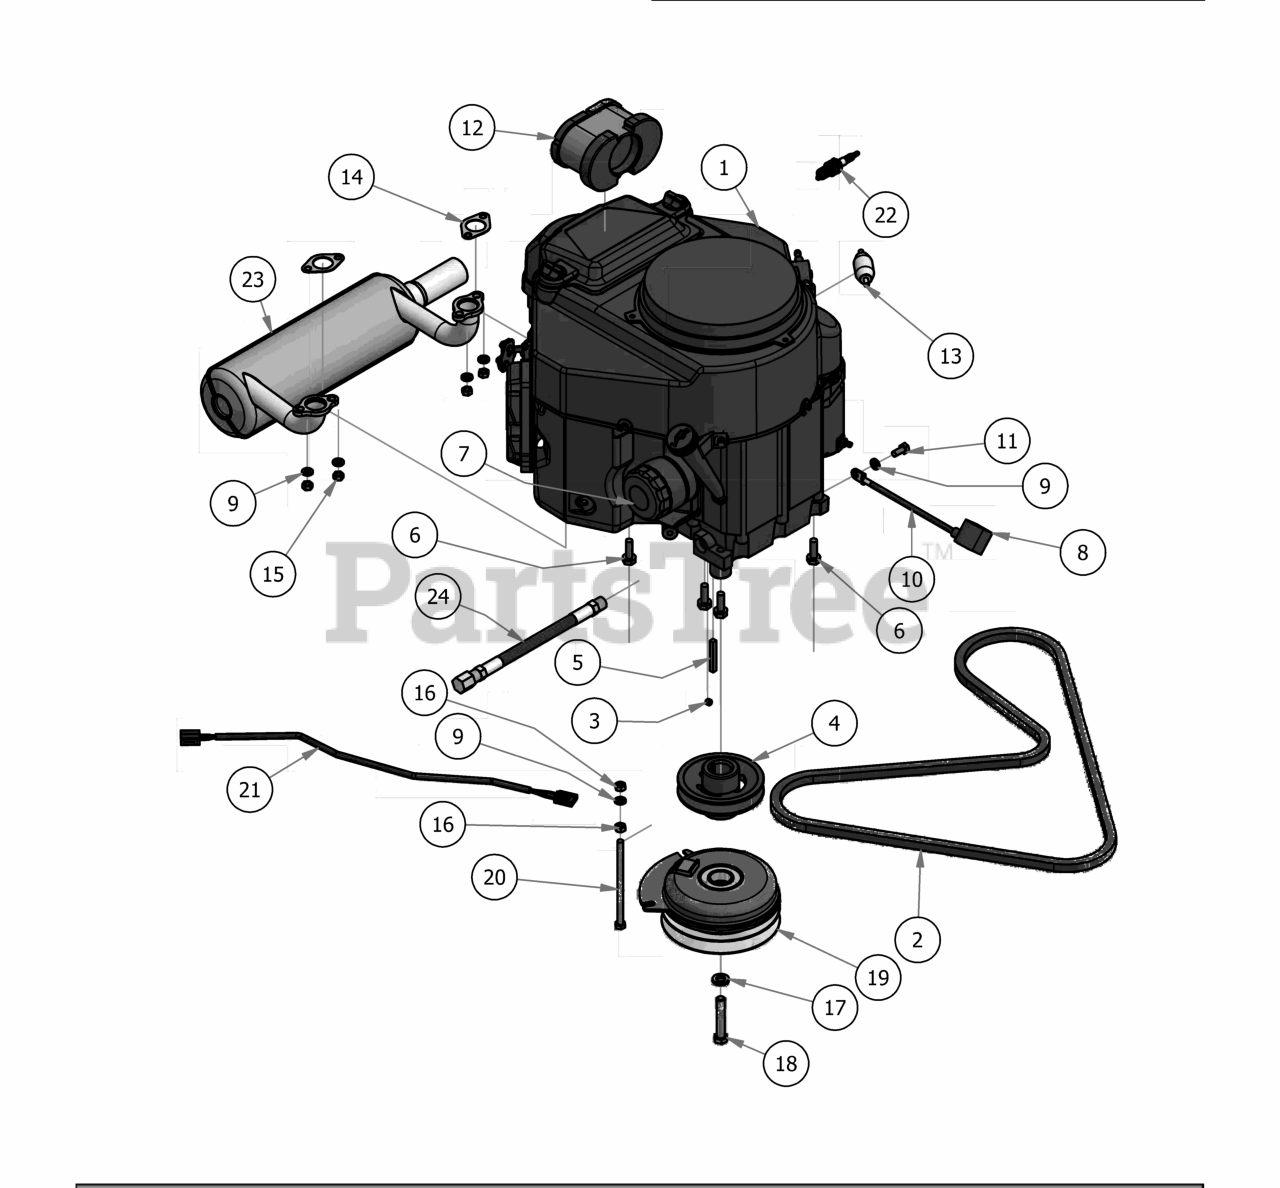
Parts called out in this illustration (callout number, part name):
1	FS730V Engine
2	75.8 Pump Belt
3	5/16 Set Screw
4	4 3/4 Motor Pulley
5	1/4 x 2 Square key Stock
6	3/8 x 1 1/8 bolt
7	Kawasaki Oil Filter
8	Black Boot For Ground Cable
9	5/16" Lock Washer
10	Ground Cable
11	M8x1.20x20MM Hex head bolt
12	Kawasaki Air Filter
13	Universal Inline Fuel Filter
14	Exhaust Gasket
15	M8-1.25 Zinc Nut
17	7/16" Lock Washer
18	7/16" x 2 1/2" Hex Bolt
19	Clutch Assembly
20	5/16-18 x 5-1/2 GR 5 Hex Bolt
21	Clutch Pigtail
22	Spark Plug - Kawasaki
23	Kawasaki Muffler 1251
24	Oil drain Hose
